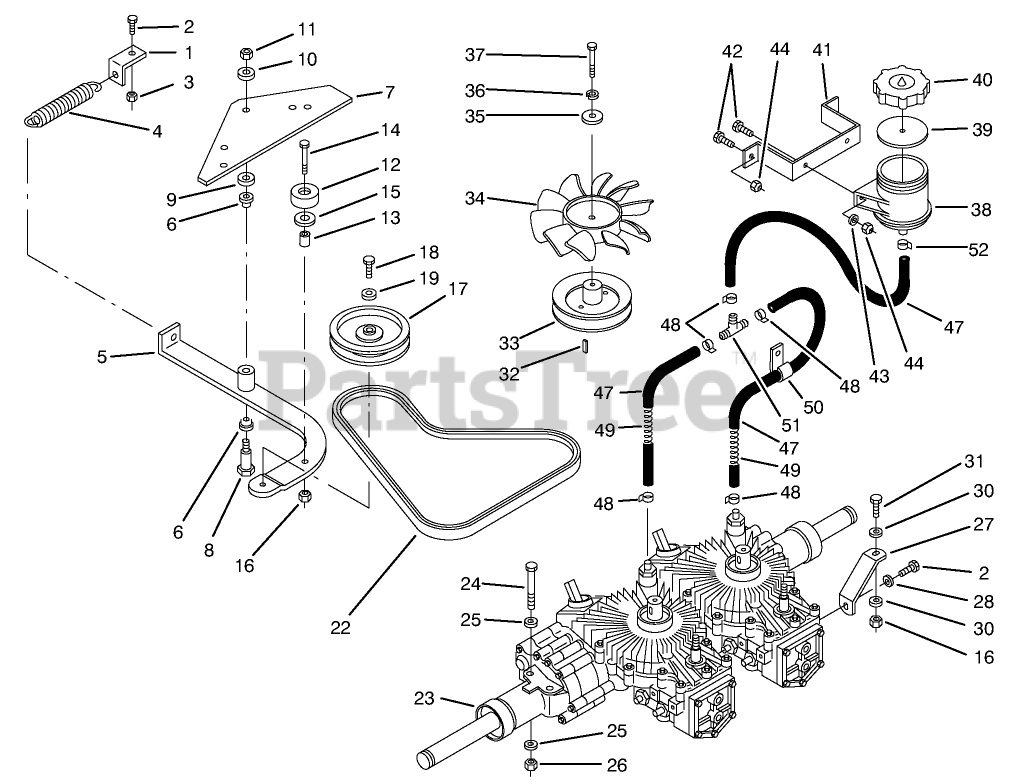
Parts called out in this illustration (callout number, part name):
1	BRACKET-SPRING
2	SCREW-HH
3	NUT-LOCK, NI
4	SPRING-EXTENSION
5	Arm-Idler
6	BUSHING
7	Stiffener
8	BOLT-SHOULDER
9	WASHER
10	WASHER-FLAT
11	NUT-HEX
12	BUMPER
13	SPACER
14	SCREW-HH
15	WASHER
16	NUT-LOCK, NI
17	PULLEY IDLER
18	SCREW-HH
19	WASHER-FLAT
22	V-BELT
23	TRANSAXLE-781
24	SCREW-HH
25	WASHER-FLAT
26	NUT-LOCK, NI
27	BRKT-HYDRO SIDE
28	Washer-Special
30	WASHER-PLAIN
31	SCREW-HH
32	KEY WOODRUFF
33	PULLEY
34	FAN-7"
35	WASHER
36	WASHER-LOCK
37	SCREW-HH
38	Reservoir w/Gasket (Incl. Ref.# 39-40)
39	COVER GASKET
40	COVER
41	Bracket
42	SCREW-HH
43	WASHER-FLAT
44	NUT-LOCK, NI
47	HOSE-7"
48	CLAMP .875
49	COMPRESSION SPRING
50	CLAMP
51	TEE-5/8 PLASTIC
52	CLAMP-HOSE
